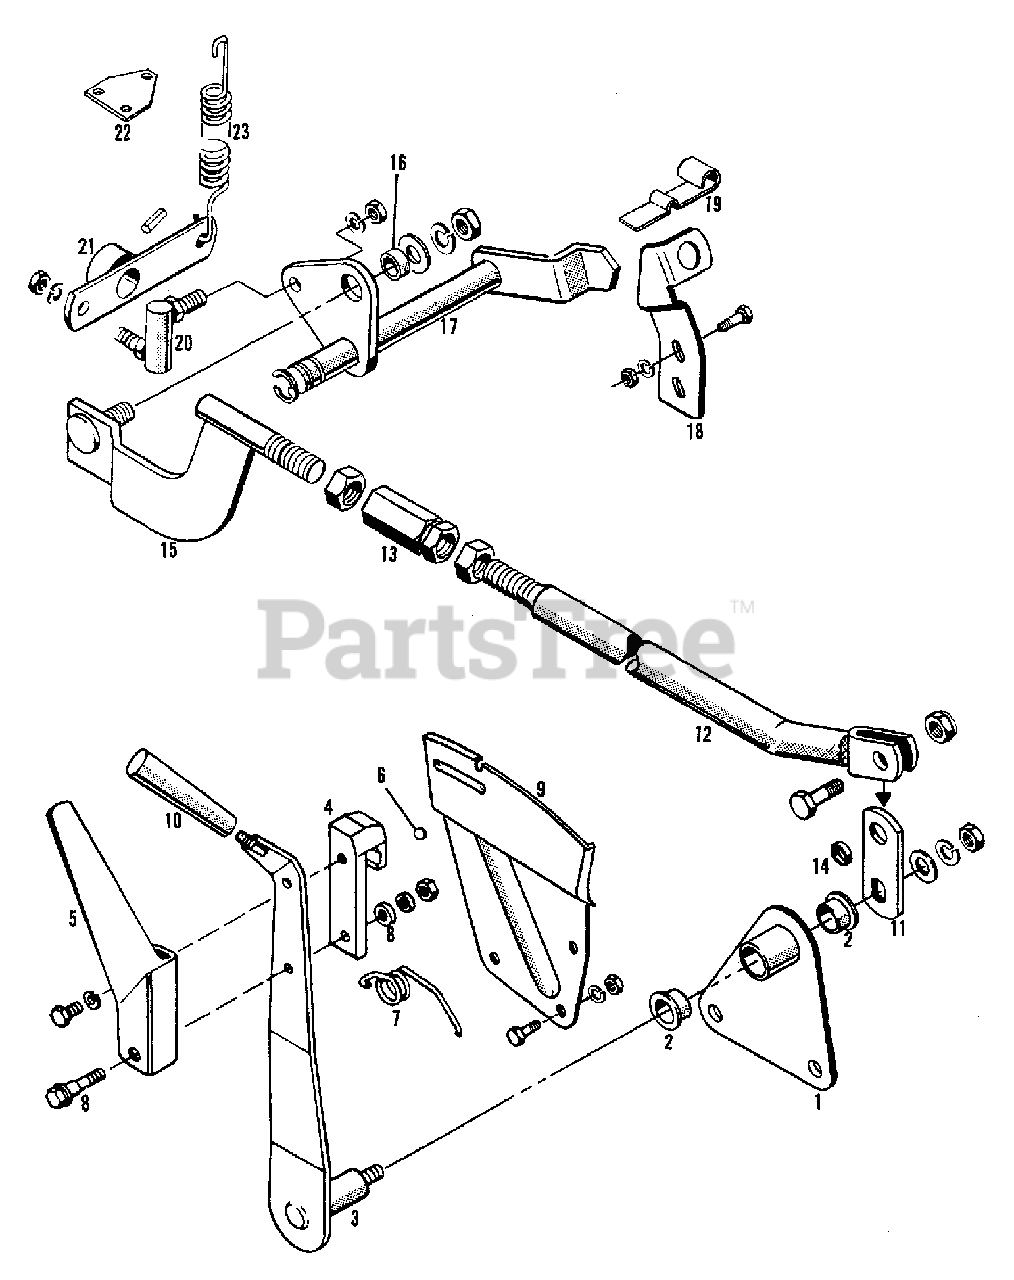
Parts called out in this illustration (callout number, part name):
1	BRACKET ASSEMBLY, Support
1	SCREW, 5/16NC x 1/2
2	BUSHING, Flanged
3	LEVER ASSEMBLY, Control
4	CLAMP, Stop
4	CAPSCREW, 1/4NC x 1/2
4	LOCKWASHER, 1/4
5	HANDLE, Trip
6	BALL, Shift Handle
8	BOLT, Shoulder
8	WASHER, 1/4
8	NUT, 1/4NC-Lock
9	PLATE, Support
9	CAPSCREW, 1/4NC x 5/8
9	LOCKWASHER, 1/4
9	NUT, 1/4NC-Speed
10	SCREW, 1/4NC x 7/8
11	CAPSCREW, 3/8NC x 1
11	WASHER, 3/8
11	LOCKWASHER, 3/8
11	NUT, 3/8NC
11	NUT, 3/8NC-Lock
12	ROD ASSEMBLY, Front Control
12	WASHER, .281 x .625 x 18 GA.
13	TURNBUCKLE
13	NUT, 1/2NF-L.H. Thread
13	NUT, 1/2NF Standard Thread
15	ROD ASSEMBLY, Rear Control (Prior S/N 26141001) (Shown)
15	ROD ASSEMBLY, Rear Control (Eff. S/N 26141001 & Up)
16	WASHER
16	LOCKWASHER, 3/8
16	NUT, 3/8NC
17	*SHAFT ASSEMBLY, Control (Prior S/N 26141001)(Shown)
17	SHAFT ASSEMBLY, Control (Eff. S/N 26141001 & Up)
17	RING, 5/8 Shaft Diameter Snap
18	SUPPORT, Switch
18	CAPSCREW, 5/16NC x 3/4
18	LOCKWASHER, 5/16
18	NUT, 5/16NC
19	CLIP, Switch
19	BOLT, Shoulder
19	WASHER, 5/16
19	LOCKWASHER, 5/16
19	NUT, 3/8NC
20	JOINT, Ball (Double End)
21	LINK ASSEMBLY, Control
21	PIN, 1/4 x 1-1/4-Spring
21	LOCKWASHER, 5/16
21	NUT, 5/16NF
22	CLIP, Spring
23	SPRING, Latch
23	SCREW, #10NF x 1/2 Round Head Mach.
